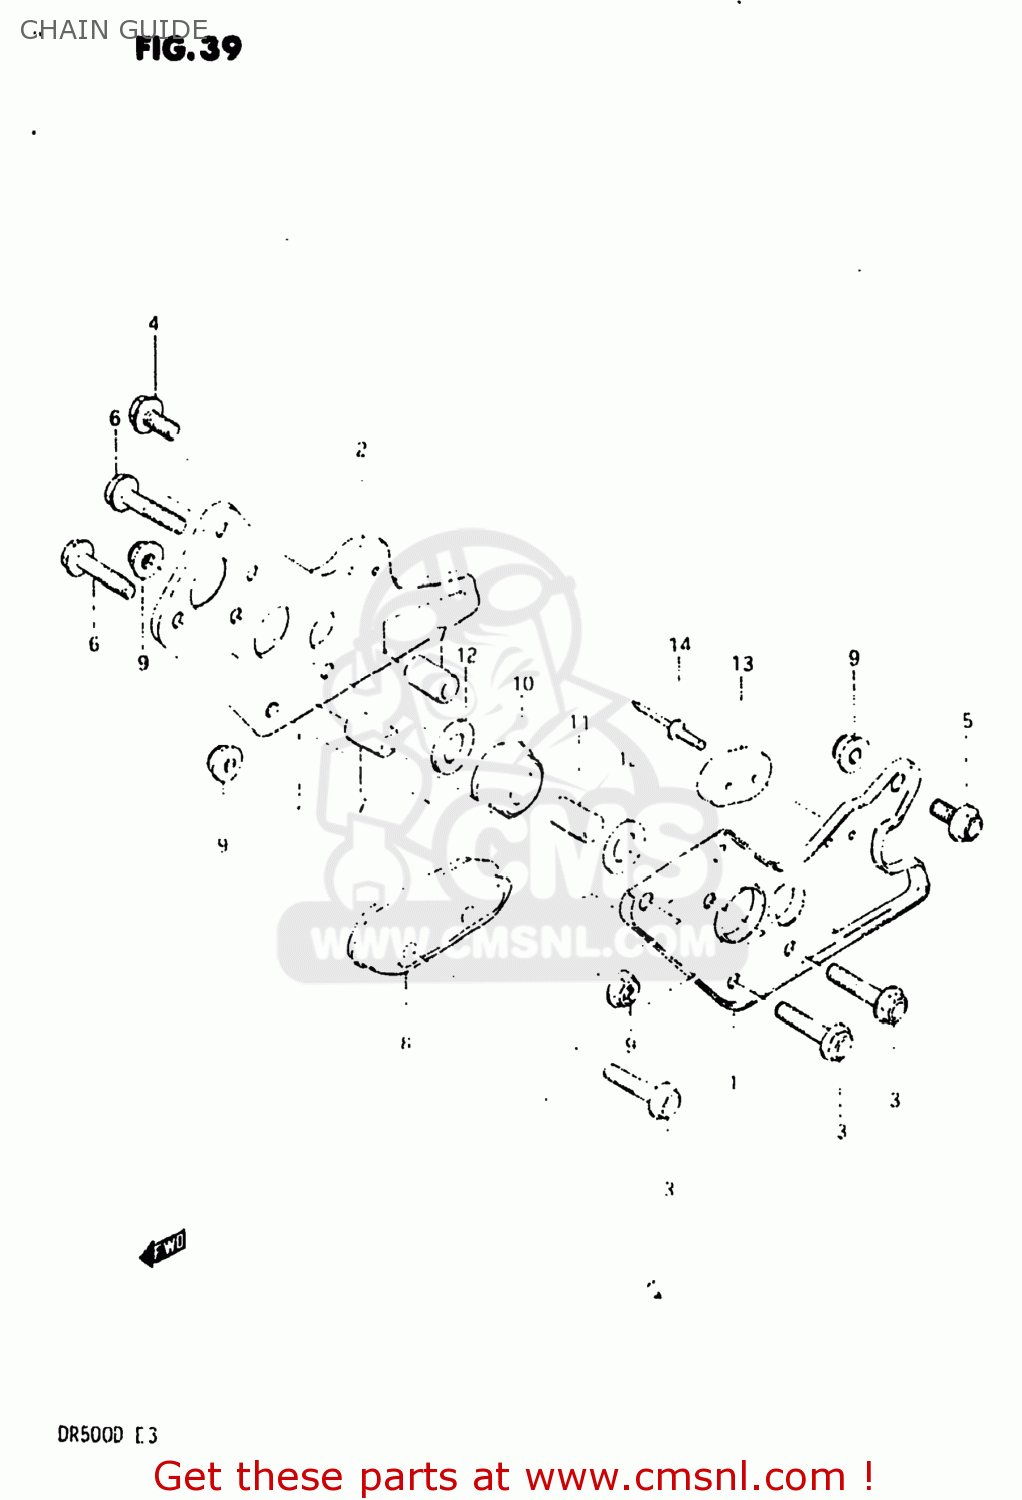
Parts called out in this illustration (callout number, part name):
1	GUIDE,CHAIN
2	PLATE,GUIDE CHAIN
3	BOLT 6X35
4	BOLT
5	BOLT
6	BOLT,UNDER
7	SPACER (6.5X10.5X25.5)
8	DEFENSE,CHAIN GUIDE
9	NUT
10	ROLLER,CHAIN GUIDE
11	SPACER,CHAIN GUIDE ROLLER
12	WASHER
13	PAD,DRIVE CHAIN GUIDE
14	RIVET
